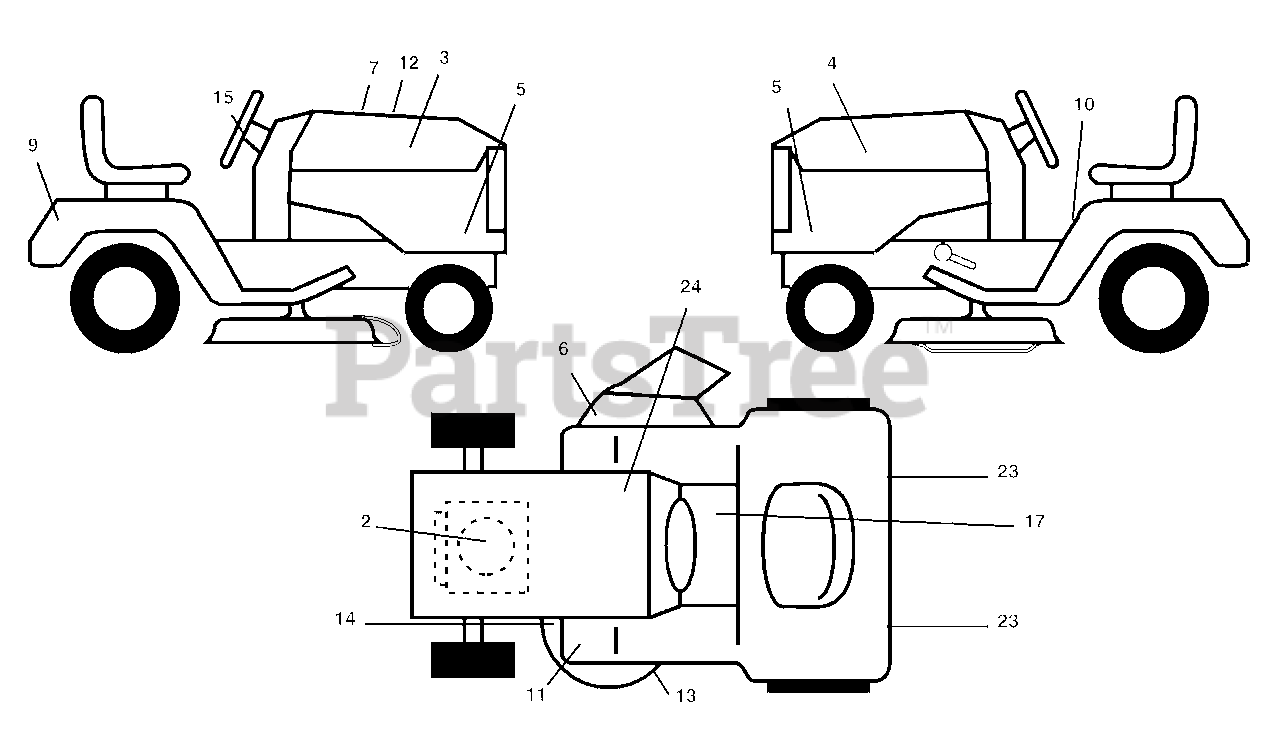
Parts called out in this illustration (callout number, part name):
1	Decal, Deck heavy Duty
2	Decal, Engine
3	Decal, Hood, RH
4	Decal, Hood, LH
5	Decal, Side Panel
6	Decal, Warning
7	Decal, Customer Resp.
9	Decal, Fender
10	Decal, Danger
11	Decal, Foot Rest
12	Decal, Replacement
13	Decal, V-Belt Sch
14	Decal, Caution
15	Decal, Ins. Strg Whl
17	Decal, Saddle Brake Parking
23	Reflector, Taillight
24	Decal, Btry Dngr/Psn
